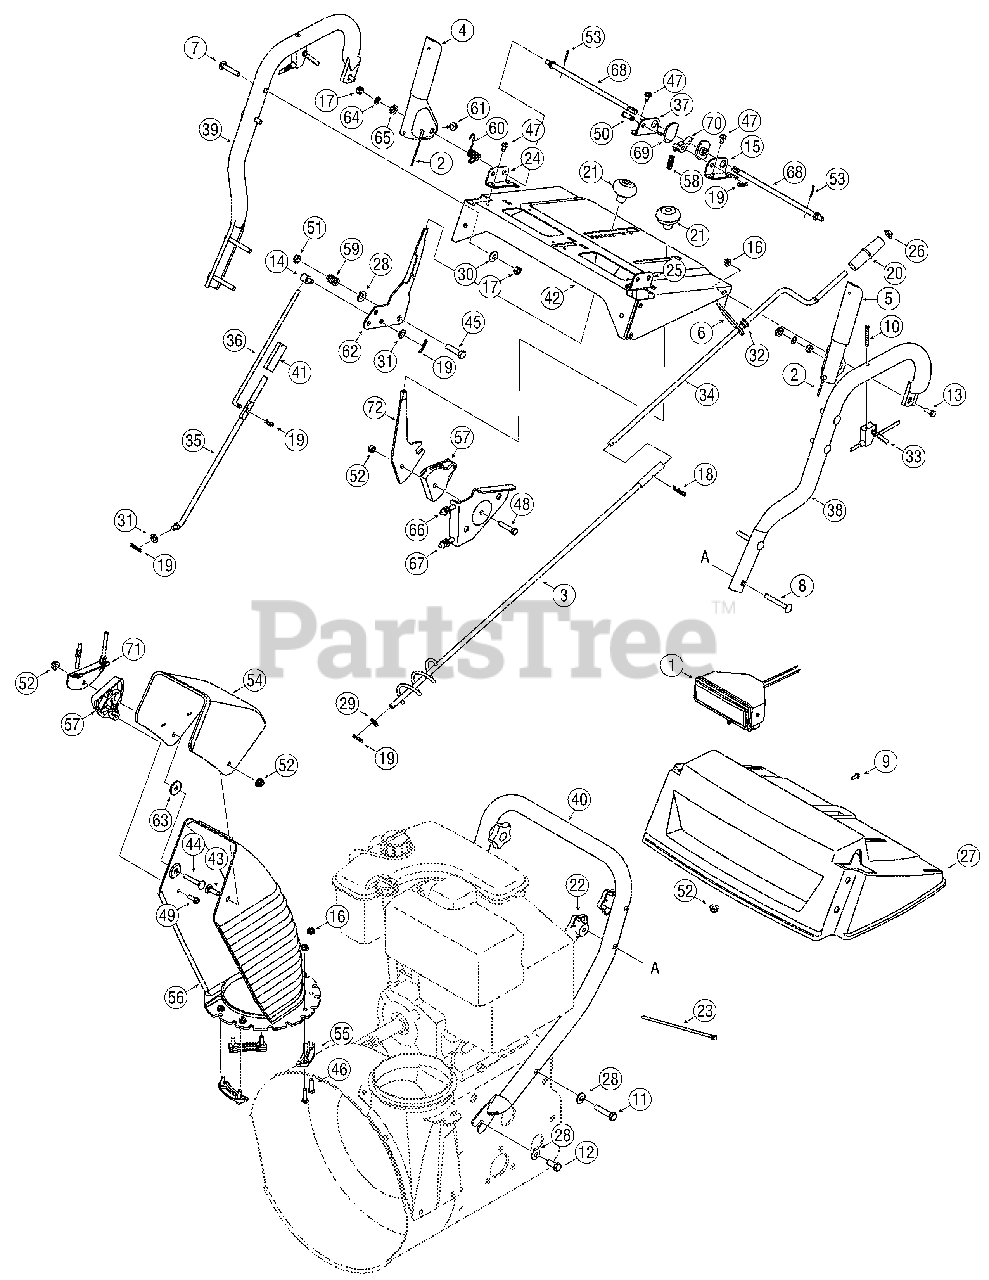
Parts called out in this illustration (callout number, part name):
1	Assembly, Light
2	Cable Ass’y, Auger/Drive
5	Handle, Engage, LH
7	Screw, Carr., 5/16-18 x 1.75
8	Screw, Carr., 5/16-18 x 2.5
9	Screw, #10-16 x .625
10	Screw, #10-24 x 1.75
11	Screw, Hex, 3/8-16 x 1,75
12	Screw, Hex, 3/8-16 x .88
13	Screw, Hex, 1/4-20 x .75
14	Ferrule, 5/16-18 x .312 Dia
16	Nut, Hex Flange, 1/4-20
17	Nut, Hex, 5/16-18 GR5
18	Pin, Internal Cotter
19	Pin, Internal Cotter
20	Knob, Crank
21	Knob, Shift
22	Knob, Star, 5/16-18
23	Tie, Cable
26	Cap, Push, 3/8
27	Panel, Handle
27	Graphic, Auger/ Chute Tilt
27	Graphic, 945 SWE
28	Wash, Bell, .375 x .87 x .063
29	Wash,Fl., .375 x .738 x .063
30	Wash, Bell, .34 x .872 x .06
31	Wash, Fl, .344 x .688 x .065
32	Bushing, Plastic, .38 ID
33	Cable Assembly, Trigger
35	Rod, Lower Shift
36	Rod, Upper Shift
41	Connector, Shift Rod
43	Screw, Carr, 5/16-18 x 1.0
44	Screw, Carr., 5/16-18 x 1.75
45	Screw, Hex, 3/8-24 x 1.5
46	Screw, Hex, 1/4-20 x 1.0
47	Screw, Hx, 1/4-20 x .5
48	Screw, Hex, 5/16-18 x 1.5
49	Screw, Hx,1/4-15 x .75
50	Pin, Clevis, .312 x 1.0
51	Nut, Insert, 3/8-24
52	Nut, Flnge Lk, 5/16-18
53	Pin, Cotter, 3/32 x .75
54	Chute, Upper, 6.0
54	Graphic, Danger
55	Flange Keeper, Chute
56	Chute, Lower
57	Cbl. Guide, Chute Tilt
58	Spring, Compression
59	Spring, Compression
60	Spring, Torsion
61	Bumper, Rubber
63	Wash, Fl, .344 x 1.125 x .12
64	Washer, Lock, 5/16
65	Wash, Fl, .35 Sq x .72 x .134
66	Cable, Chute Control, 66"
67	Cable, Chute Control w/Clip,
69	Cam, Handle Lock
70	Pawl, Handle Lock
